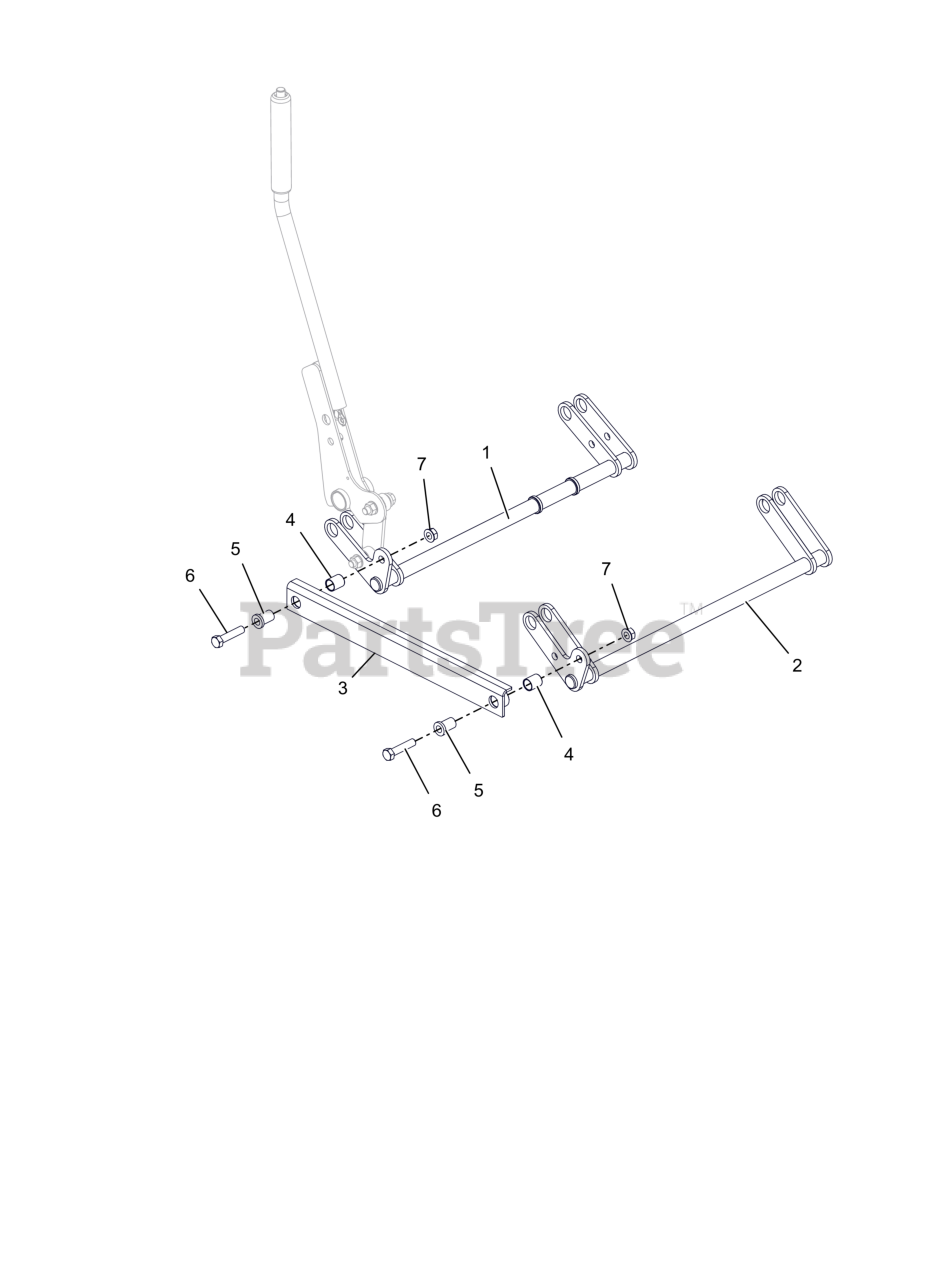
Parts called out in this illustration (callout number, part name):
1	WLDMT, 36" PROSTANCE DECK LIFT (BLACK)
2	WLDMT, 36" PROSTANCE DECK LIFT
3	LINK, 36" DECK LIFT
4	BRG, .750 X .875 X 1.000
5	BSHG-FLG .515X.746X1.290X1.000
6	BLT, HEX .50-13X2.25 G5 ZCC
7	NUT-LK-CTR-FLG .500-13 GG ZCC
